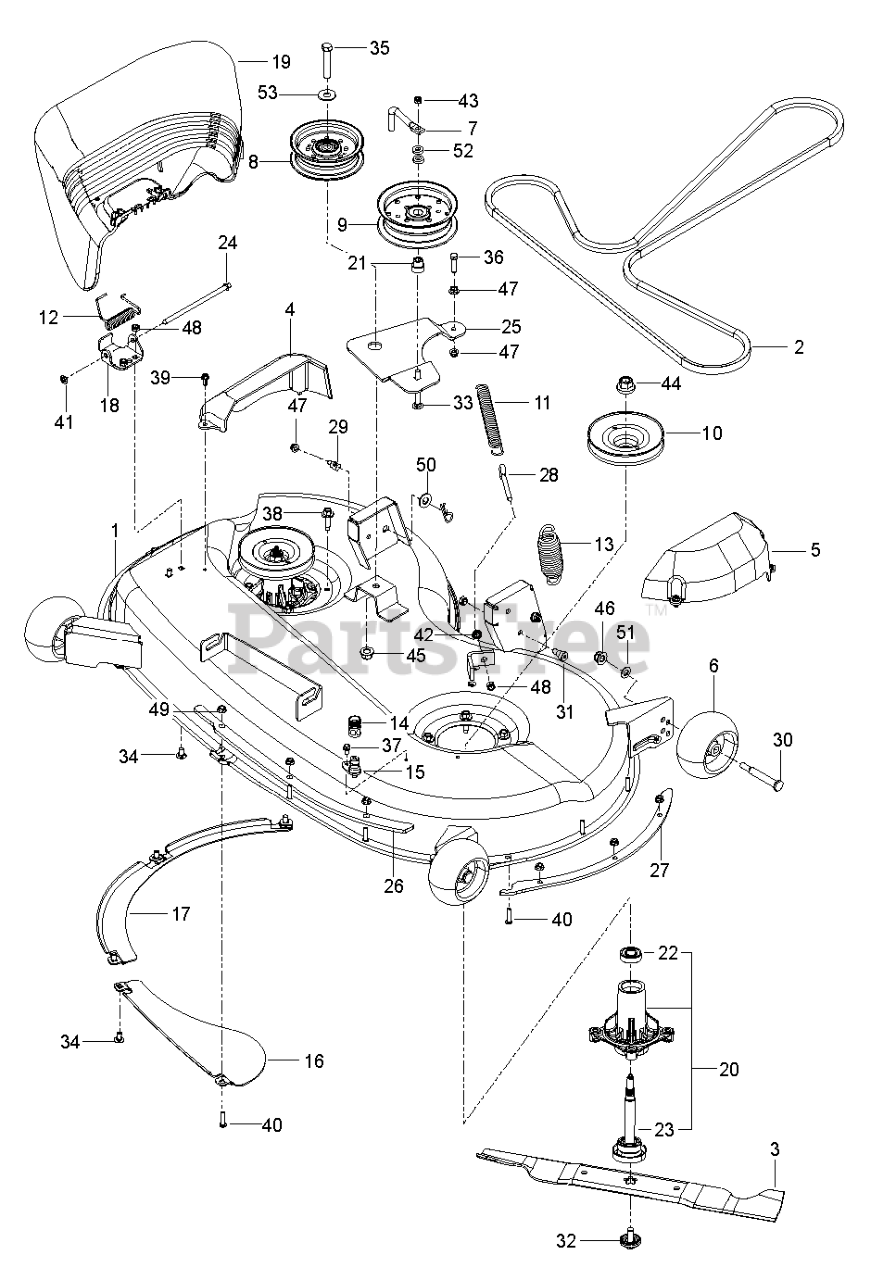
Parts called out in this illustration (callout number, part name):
1	DECK W/DECALS - RZ46
3	BLADE.MOWER.46".HI.LIFT
4	COVER.MANDREL.RH.46"
6	WHEEL.GAUGE.RALLY
7	BELT KEEPER 5"
8	PULLEY.IDLER.MWR.STATI.LH
9	PULLEY.IDLER.DECK
10	PULLEY.MANDREL.46"
11	SPRING.EXTENSION
12	SPRING, TORSION
13	SPRING
14	COUPLING.QUICK CONNECT
15	PORT.WASHOUT
16	BAFFLE CENTER FRONT
17	BAFFLE FRONT RH
18	BRKT.DEFLECTOR.38"2005+
19	SHIELD.DEFLECTOR.MOWER.46"BLAC
20	MANDREL.W/SPCR.BRG.SHRT.NONRVL
21	IDLER BUSHING
22	BEARING.MANDREL.TOP.EXTENDED
23	SHAFT
24	ROD.HINGE
25	ARM.PNT.CLTCHG.STMP.46.RZ.EDIP
26	PLATE.PNT.REINF.DECK.46".EDIP
27	PLATE.REINFOR.46.SIDEBOLT.X431
28	EYE BOLT 5/16 X 3.50
29	STUD.FASTNER.W/ANTI-ROTATE
30	BOLT.SHOULDER.3/8-16X3-5/8.
31	SB 3/8-16 X 3/8 SKT HD ZD
32	SCREW.SEMS.7/16-20X1.HEX.HEAD
33	BOLT CARRIAGE
34	RP BOLT 5/16-18 X3/4 ZN/YEL GR
35	BOLT.HEX.7/16-14
36	BOLT.5/16-18X1-1/4 FULL THD
37	SCREW #10 X 1/2 SELF TAPPING
38	BOLT.HEX.WASHR.HED.313-18X1.19
39	SCREW.1/4-20X5/8
40	SCREW.BUTTONHEAD.1/4-20X1
41	NUT PUSH M
42	NUT 5/16C WHIZ
43	NUT HEX 3/8-16 NYLON, THIN
44	NUT.FLANGE.LOCK.TOP
45	NUT.LOCK.FLANGE.7/16
46	NUT LOCK FLG 3/8-16 UNC
47	5/16-18 NYLOC FLANGE NUT
48	NUT.71038.31-18.HEX.NYLOCK
49	NUT T
50	WASHER
51	WASHER 5/16 FLAT
52	WASHER 3/8 X 3/4 X .187 TK
53	WASHER 7/16 FLAT ZD
